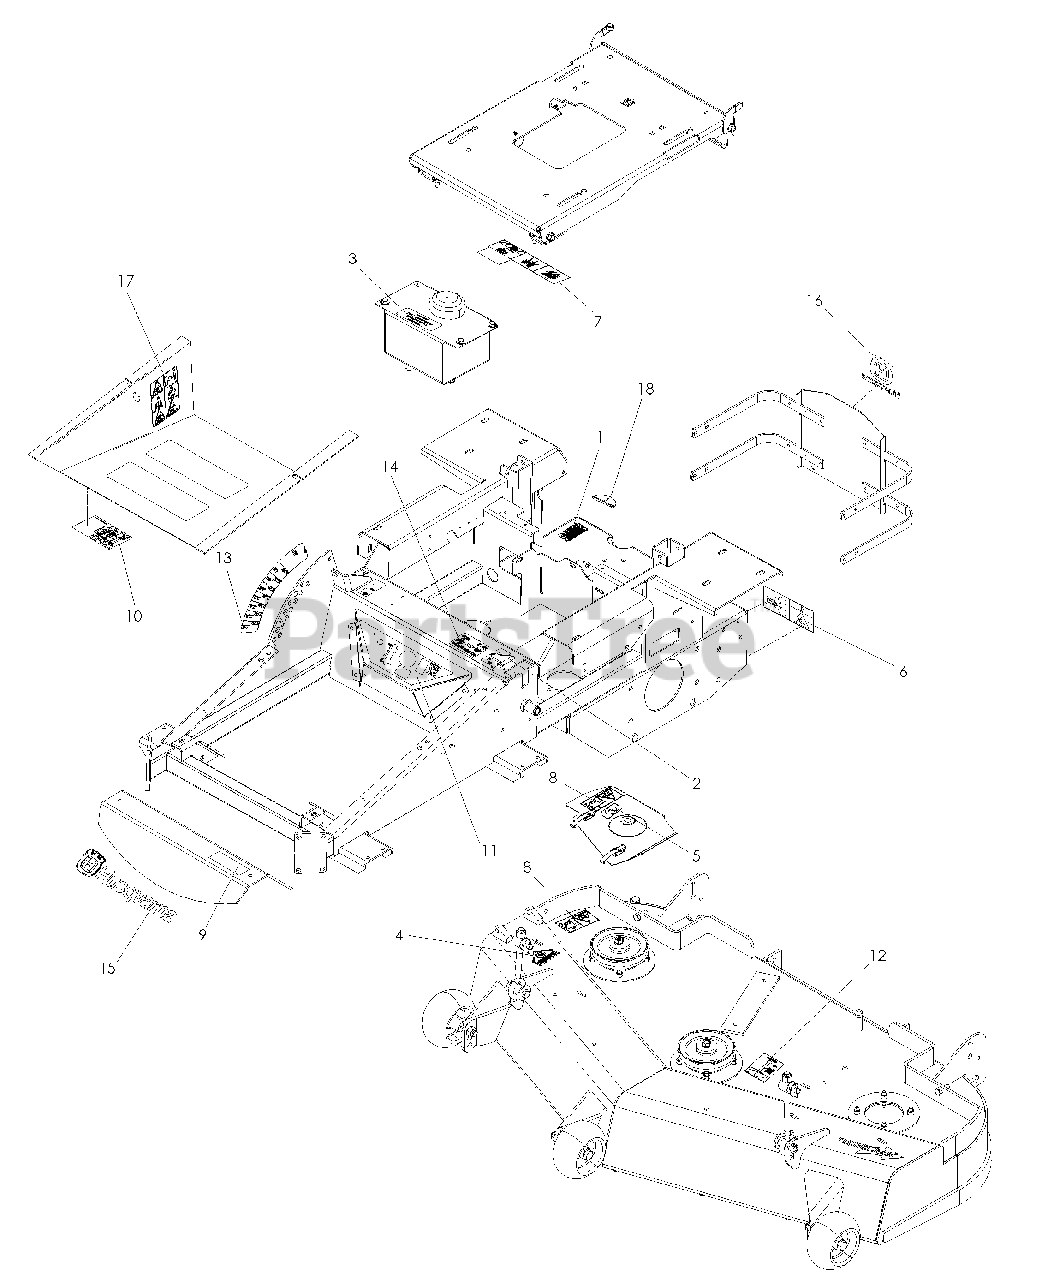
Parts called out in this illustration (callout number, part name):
1	DECAL, PROP 65
2	DECAL, MOTION CONTROL
3	DECAL, OIL TANK
4	DECAL, WARNING
5	DECAL, NO STEP
6	DECAL, DANGER, BLT
7	DECAL, BATTERY WARN
8	DECAL, SEVERING
9	DECAL, IZ4217
9	DECAL, IZ4819
9	DECAL, IZ4821
9	DECAL, IZ5223
9	DECAL, IZ5225
9	DECAL, IZ6125
9	DECAL, IZ25
9	DECAL, SERVICE
10	DECAL, CONSOLE
11	DECAL, BELT ROUTING
12	DECAL, HEIGHT ADJ
13	DECAL, H.S.T.
14	DECAL, HUSQVARNA
15	DECAL, CROWN
16	DECAL, WARNING
17	DECAL, FUEL VALVE
